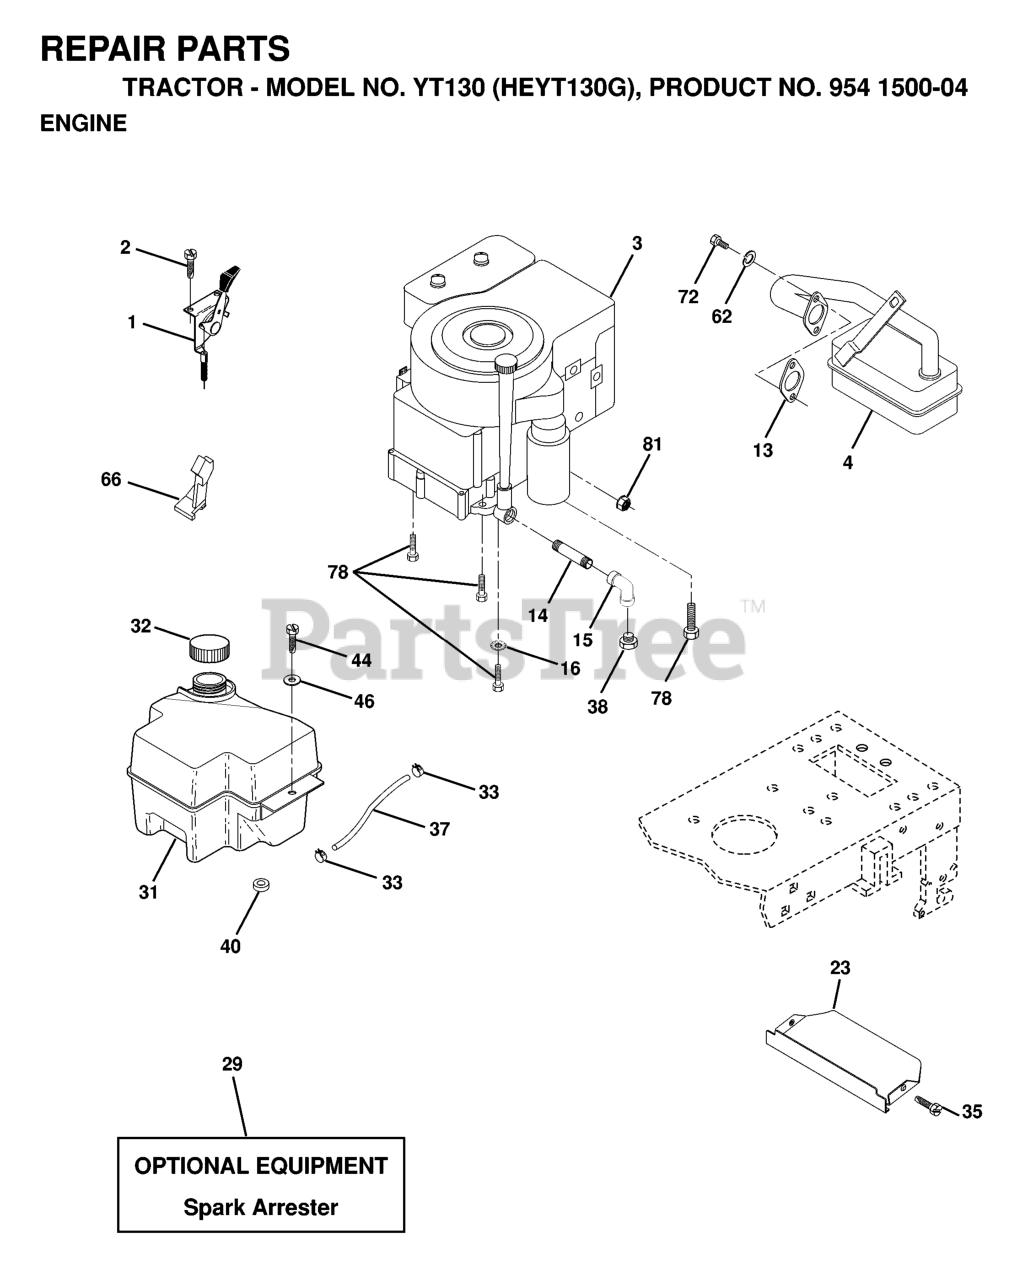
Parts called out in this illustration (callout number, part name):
1	CONTROL
2	SCREW LT
4	MUFFLER.SINGLE.B&S.10-12HP
13	GASKET.ENG.1.313 ID.TIN PLATED
14	Nipple Pipe 3/8 Npt X 3-1/2
15	ELBOW
16	LOCKWASHER
29	KIT.SPARK ARRESTOR 794945 B&S
31	FUEL TANK
32	FUEL CAP
33	HOSE CLAMP
35	SCREW.THDROL.5/16-18X3/4.TTY
37	LINE.FUEL.20
40	BUSHING.SNAP.NYL.BLK.
44	SCREW HEX CRT
62	WASHER.LOCK.HVY.HLCL.SPR.5/16
66	STOP THROTTLE
72	SCREW
78	SCREW
81	NUT FLANGE 1/4-20 STARTER NUT
